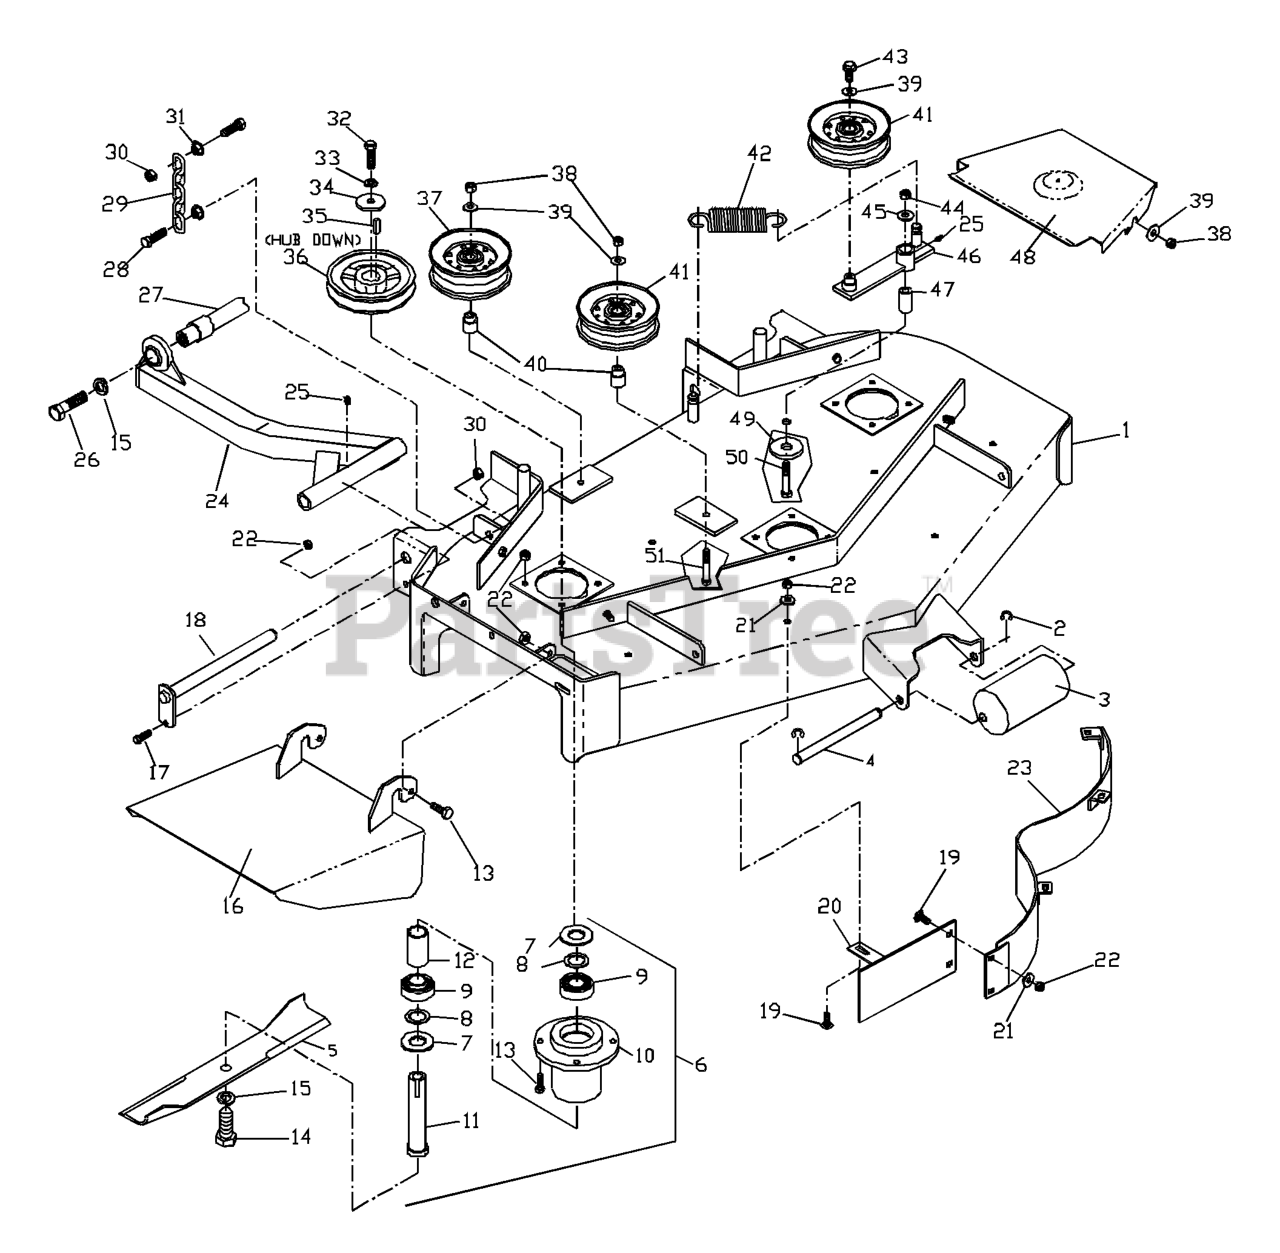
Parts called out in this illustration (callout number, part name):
1	DECK W/DECALS HUS
2	E-RING 1/2 (2 2)
5	BLADE OEM, 14-7/8
6	HOUSING, COMPLETE
7	MACHINERY BUSHING 10 GA.
8	BUSHING.MACHINE.18.GAUGE
9	BEARING
11	SPINDLE SHAFT
13	HCS 5/16C X 1
14	HCS 5/8F X 1 1/4
15	LOCKWASHER 5/8
16	DISCHARGE CHUTE 42"
17	HCS 5/16C X 3/4
19	CARRIAGE BOLT 5/16C X 5/8"
20	CENTER BAFFLE
21	WASHER 5/16 FLAT
22	NUT 5/16C CENTERLOCK
23	MAIN BAFFLE
24	STRUT WLDMT - RT
24	STRUT SLDMT-LT
25	ZERK
26	HCS 5/8C X 2 GR.5
27	STRUT MOUNT WELDMENT
28	HCS 7/16C X 1 1/2
29	LIFT CHAIN
30	NUT 7/16C CENTERLOCK
31	NUT 7/16C WHIZ
32	HCS 7/16F X 1 1/2
33	WASHER 7/16 LOCK
34	WASHER, CRANKSHAFT
35	KEY 1/4 SQ X 1 1/8
37	IDLER PULLEY (TALL)
38	NUT 3/8C CENTERBLOCK
39	WASHER 3/8 FLAT
40	IDLER BUSHING
41	IDLER PULLEY
43	4CS 3/8C X 1 SERRATED HEAD
44	NUT 1/2-13 HEX NYLOC ZD
45	WASHER 1/2 FLAT
47	PIVOT BUSHING
48	BELT SHIELD
49	WASHER, SUPPORT
50	HCS 1/2C X 3 1/4
51	HCS 3/8C X 2 1/2
52	BELT, DECK 42"
53	DECAL, NO STEP
54	DECAL, CPSC
55	DECAL, DANGER
